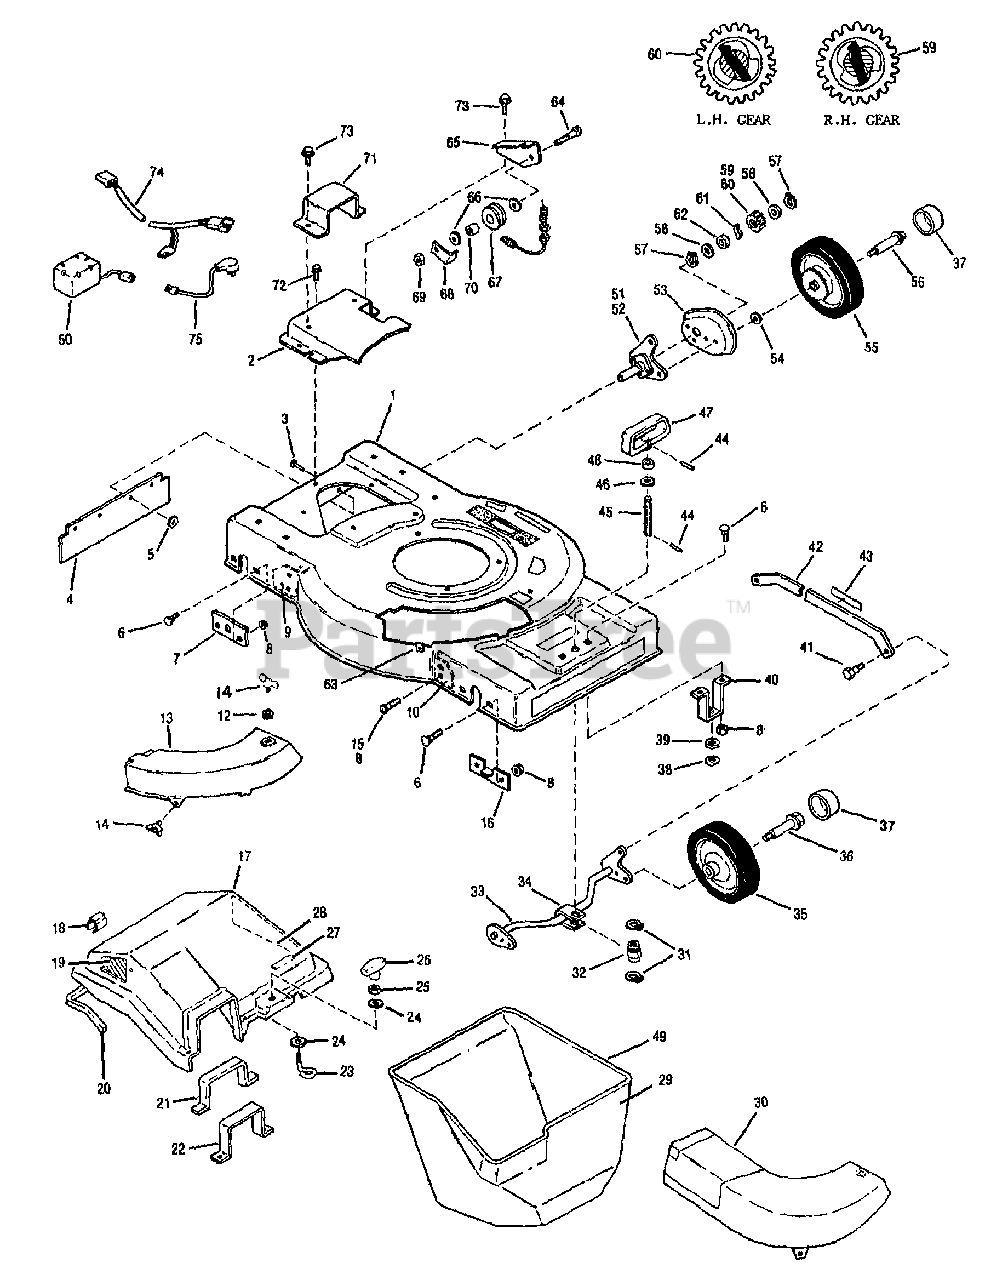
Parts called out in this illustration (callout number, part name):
1	BASE-MOWER STD START
1	BASE-ELEC MOWER
2	COVER-TRANSMISSION
3	RIVET-POP 3/16"DIA
4	SHIELD-REAR
5	WASHER-.188
6	SCR-CARR 5/16-18X.62 G2
7	HUB-SUPPORT WHEEL
8	NUT-HFLK 5/16-18
9	ASSM-BAFFLE REAR
10	ASSM-BAFFLE FRONT
11	THIS REF. NO. NOT USED
12	GROMMET-PLASTIC
13	COVER-DECK
14	SCR-WING 1/4-20 X 1/2"
15	SCR-TRUSS HD 5/16-18X.62
16	BRACKET-AXLE
17	ASSM-COVER (INCL. 18-28)
18	CLIP-HANDLE
19	SCREEN-SMALL
20	COVER-SEAL
21	SEAL-CHUTE
22	SUPPORT-CHUTE
24	WASHER-FLAT 1/4 SAE
25	NUT-HEX 1/4-20
27	PLATE-LOGO
28	SCREEN-LARGE
29	BAG WITH TAG
30	ASSM-BODY CHUTE COVER
31	RING-RET "E" .668 ID
32	NUT-HGT ADJUSTMENT
33	ASSM-FRONT AXLE
34	CHANNEL-HGT ADJUSTMENT
35	ASSM-WHEEL/TIRE FRONT
37	CAP-HUB
38	WASHER-FLAT .88X.5X.06
39	WASHER-1.0X.53X.06 NYLON
40	BRKT-HGT ADJ
41	BOLT-SHOULDER GR. 5
42	LINK-HGT ADJ
43	DECAL-HT ADJ
44	PIN-ROLL .188X1.0
45	SCR-HGT ADJ
46	WASHER-WAVE .81X.51X.016
47	HANDLE-HEIGHT ADJ
49	FRAME W/BAG
50	KIT-BATTERY REPLACE
51	ASSM-WHEEL HUB RH
52	ASSM-WHEEL HUB
53	COVER-DRIVE WHEEL
54	WASHER-.88X312X.08
55	ASSM-WHEEL/TIRE REAR
56	BOLT-SHOULDER-GR. 5
57	RING-RETAINING
58	WASHER-FLAT 1.0X.516X.031
59	GEAR-DRIVE RH
60	GEAR-DRIVE LH
61	DOG DRIVE
62	SPACER-DR GEAR .936X.50X.143 P
63	NUT-SPEED
64	SCR-HH 1/4-20X1.0
65	SUPT-CABLE
66	WASHER-FLAT 1.25X.28X.062
67	CABLE-PULLEY
69	NUT-LK 1/4-20
71	BRKT-BATTERY
72	SCR-HH 1/4-20X.625
73	SCR-FLANGE 1/4-20X3/4 GR5
74	HARNESS-WIRING ELECTRIC START
75	CHARGER-BATTERY (ELECTRIC START)
